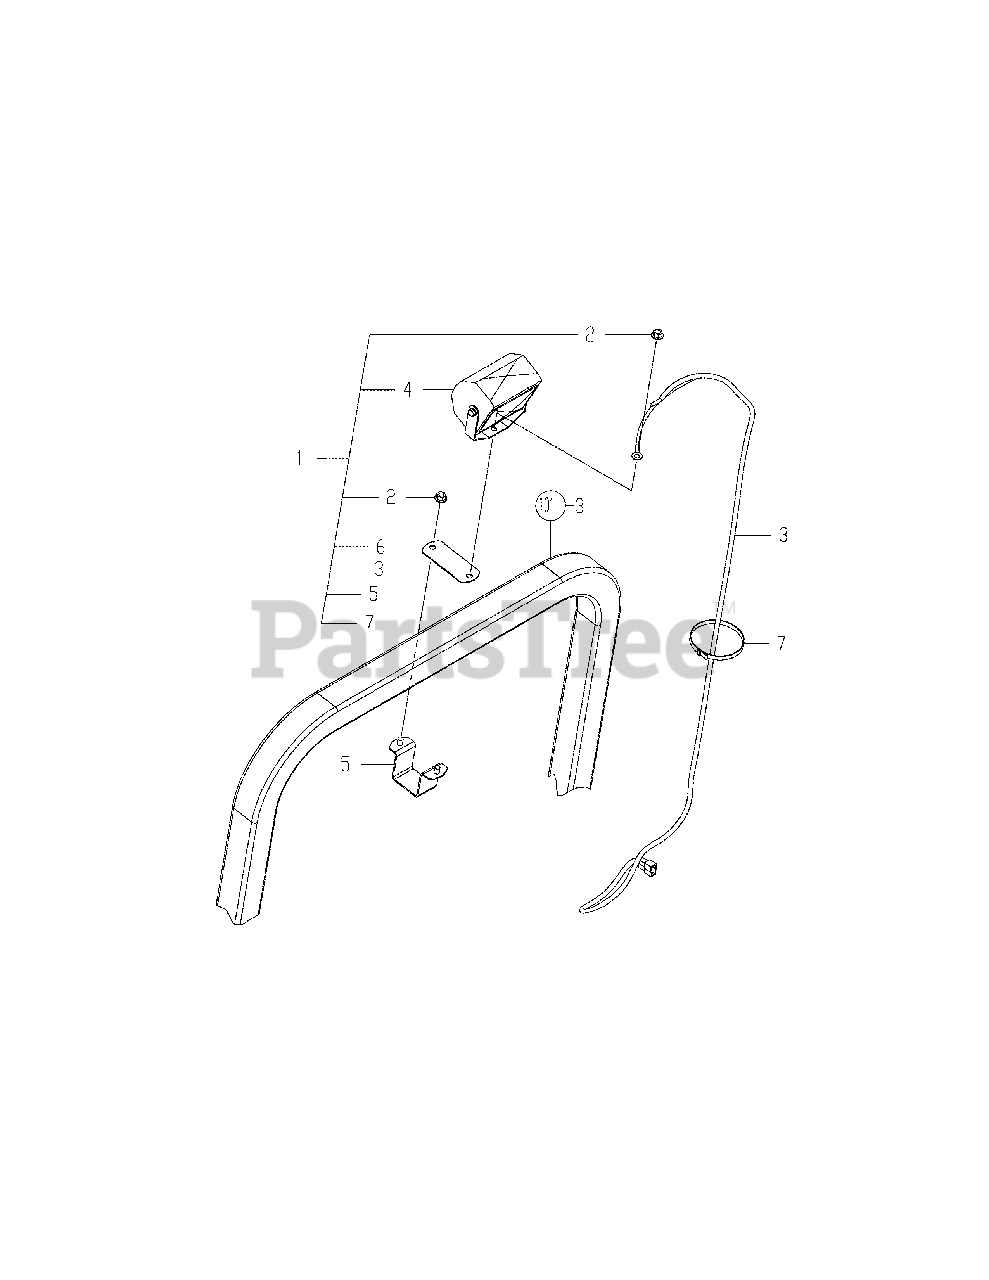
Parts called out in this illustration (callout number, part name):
1	Lamp Kit, Work
3	Cable, Work Assy
4	Lamp, Work Assy
5	Stay A,Work Lamp
6	Stay B,Work Lamp
